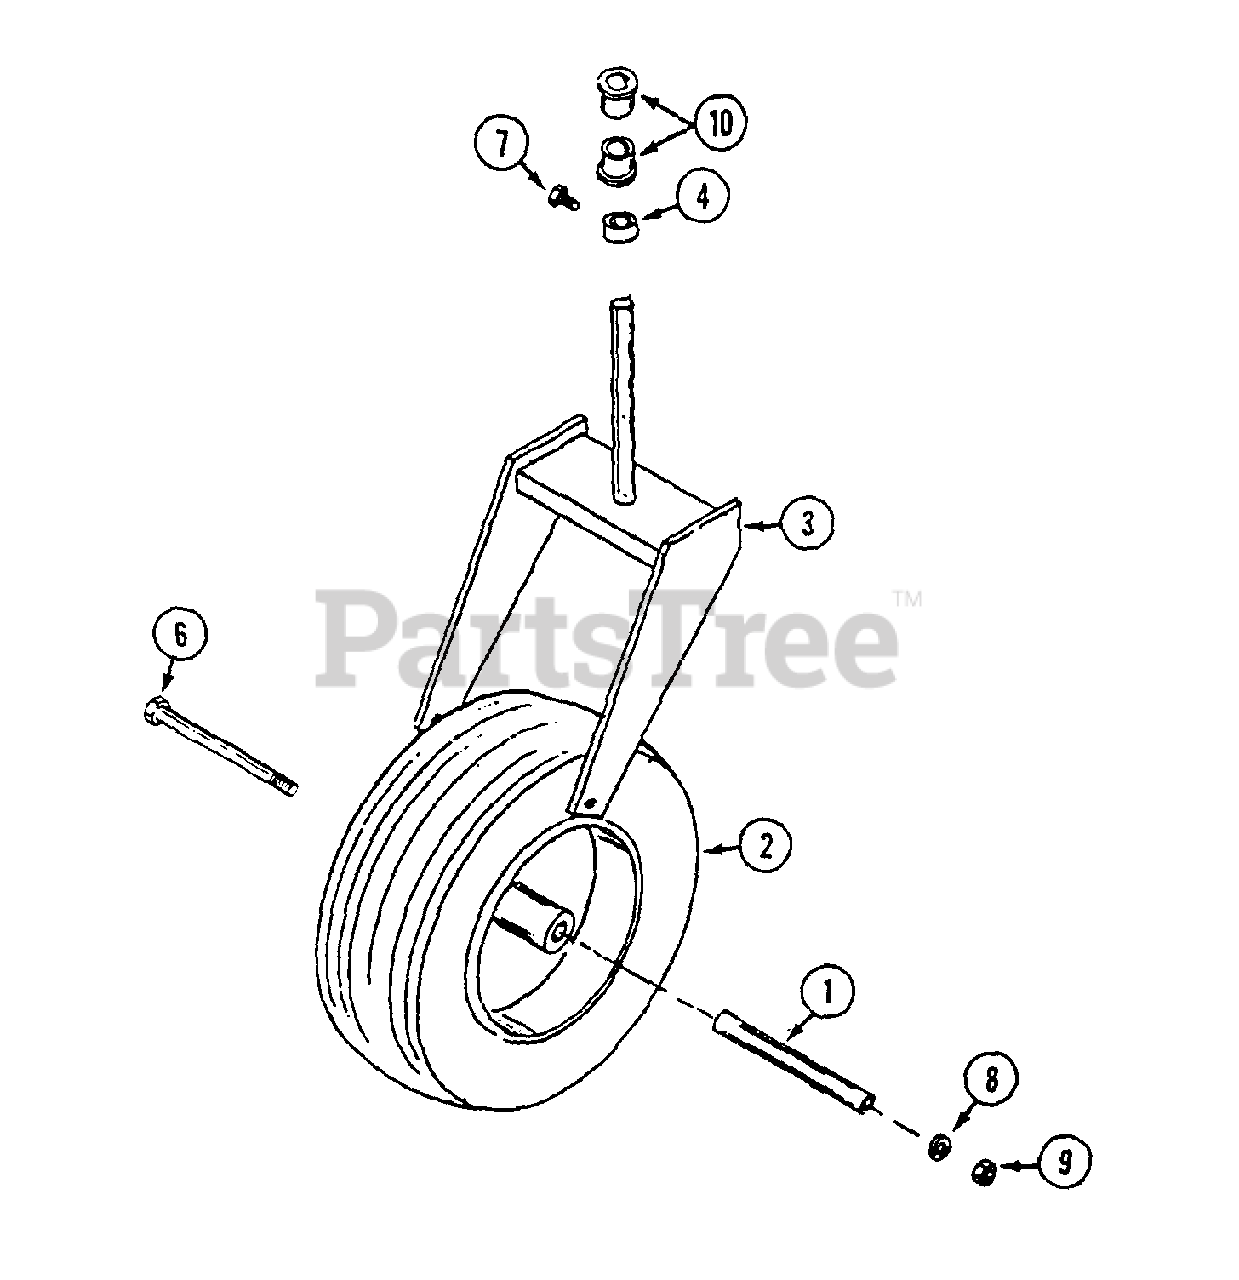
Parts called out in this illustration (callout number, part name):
2	WHEEL ASSEMBLY - tail
3	FORK - tail wheel
4	COLLAR - set 1"
6	BOLT - 1/2" - 13 x 9-1/2"
7	SCREW - set 5/16" - 18 x 1/2" square head
8	LOCKWASHER - 1/2"
9	NUT - 1/2" - 13
10	BEARING - ball 1"
